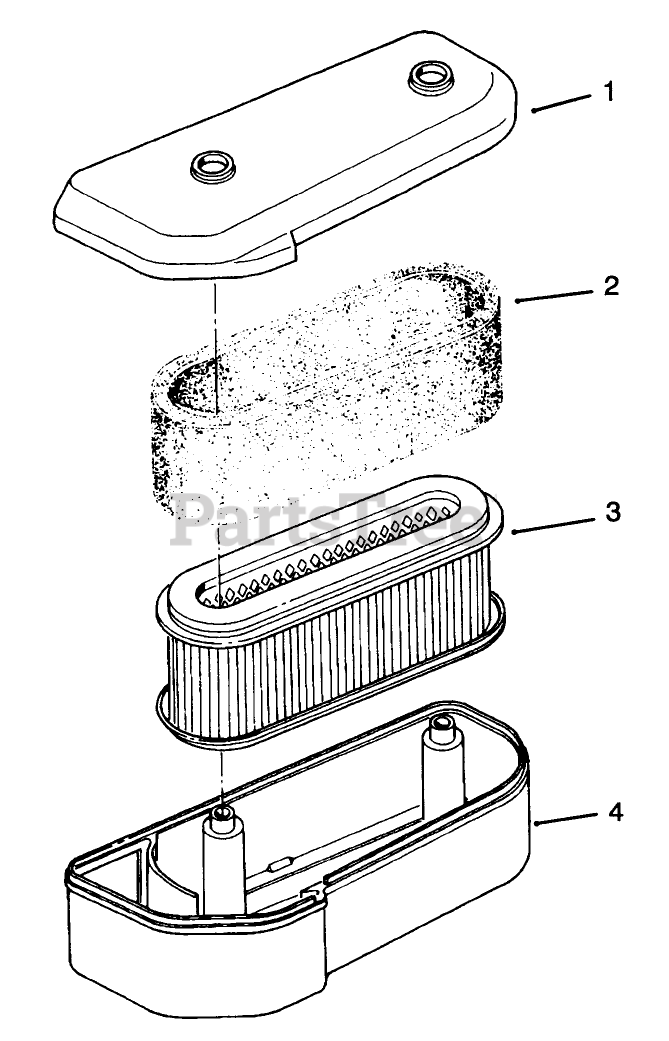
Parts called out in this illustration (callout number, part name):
1	CAP-Air Filter
2	Element
3	Element
4	CASE-Air Filter
